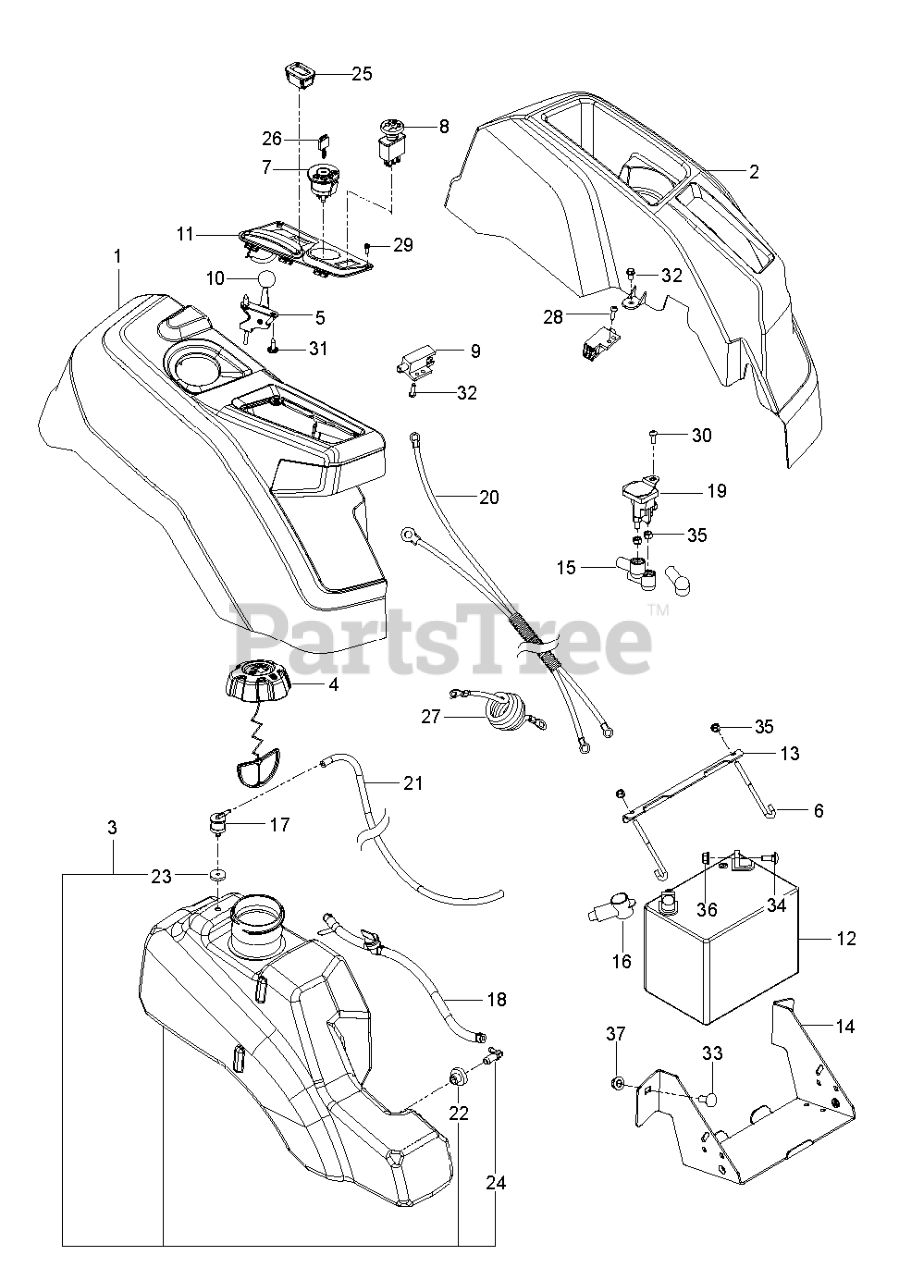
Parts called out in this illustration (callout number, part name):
1	CONSOLE.ASSY.RZ.REFRESH.RH
2	CONSOLE.LH.ASM
3	ASM.FUEL.TANK.LG.3".W/O SHIELD
4	CAP ASSY FUEL 3" GRAY
5	CABLE.THROTTLE.37"
6	HOOK.J.BATTERY
7	RP IGNITION SWITCH
8	RP SWITCH.PTO.TERMINAL.STD.RED
9	SWITCH.INTLK.RZ.RFRSH.BUTTON
10	KNOB.ROUND.BALL.BLACK
11	CONTROL.PANEL.RZ.REFRESH.RH
12	BATTERY, 12 V 300 AMP DRY
13	BRACKET.PNT.MOUNT.BATTERY.EDIP
14	BOX.PNT.BATTERY.RZ.EDIP
15	TERMINAL COVER
17	VALVE.FUEL.CHECK
18	FUEL.HOSE.SHUT.OFF.ASM.10".3"
19	SOLENOID.STARTER.BRASS.PLUNGER
20	HARNESS.BTTRY.CABLE.RZ.REFRESH
21	HOSE.3/16".VAPOR.LINE.18"LGTH
22	BUSHING OUTLET T
23	GROMMET.ROV.SENTEC
24	STEM FUEL TANK
25	GUAGE.SRVCMNDR.HRMTR.
26	KEY MLD GEN DELTA
27	CABLE POSITIVE, LONG
28	SCREW.BUTTONHD.10-24X1/2.(2 2)
29	SCREW 6-19X.437
30	SCR 1/4-20 X 5/8 BTN SKT HD ZD
31	SCREW.PAN.HEAD.#10
32	SCREW
33	RHSNB 3/8C X 1
34	RP BOLT 5/16-18 X3/4 ZN/YEL GR
35	NUT.1/4-20.HEX.NYLOC.ZD
36	5/16-18 NYLOC FLANGE NUT
37	RHSNB 3/8C X 1
